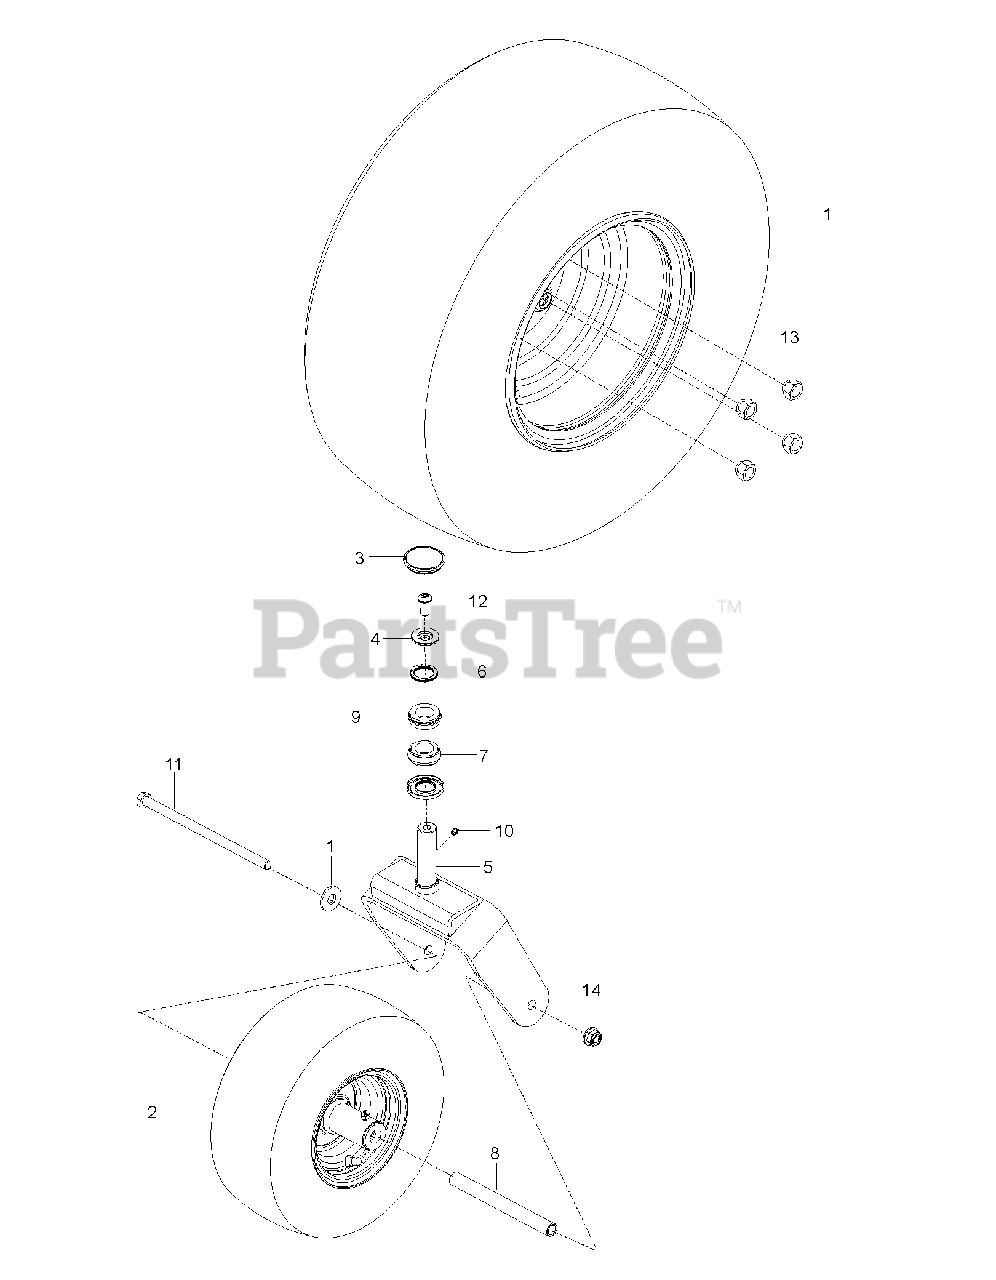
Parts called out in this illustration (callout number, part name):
1	Wheel Assembly, 20 X 10-1
2	TIRE.ASSEM.CASTER.13X6.5-6.SIL
3	CAP DUST YELLOW ZINC
4	CAP SPRING. MZ/MZT CASTER RAW
5	FORK CASTER, MZT ORANGE X668
6	SPRING NESTED WAVE MZ/MZT
8	SPACER, PIVOT
9	TAPERED ROLLER BRG
11	HEX SCREW 1/2-13 X 9.5 GR5
12	SCREW HEXALOBULAR SOCKET BUTTO
13	NUT.1/2-20.UNF-2B.GR.8.YL
14	NUT, 1/2-13 HEX FLG NYLOC ZD
15	WASHER.9/16 X 1 3/8 X 12 GA.
